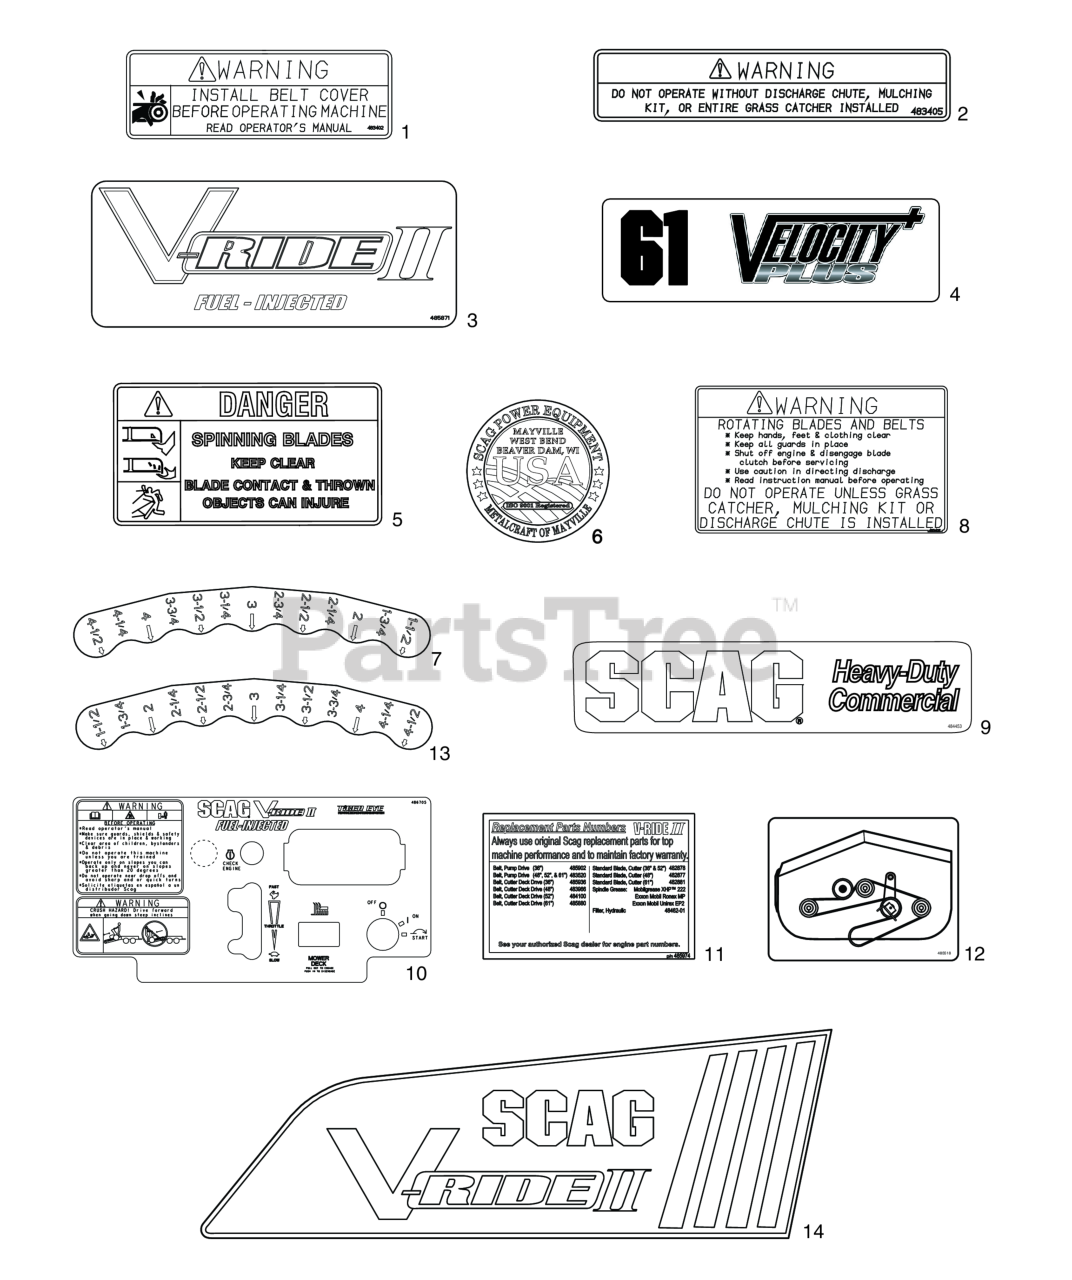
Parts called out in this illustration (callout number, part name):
1	Decal, Warning - Belt Cover
2	Decal, Warning-Discharge
3	Decal, Belt Cover
4	Decal, 36 Advantage 483060
5	Decal, Spinning Blades
6	Decal, Metalcraft - USA
7	Decal, Deck Height - Outer
8	Decal, Warning - Rotating Blades
9	Decal, Scag Heavy Duty Commercial
10	Decal, Instrument Panel - SVRII-32A/36A
11	Decal, SVRII Replacement Parts
12	Decal, Belt Routing - SVRII36A
13	Decal, Deck Height - Inner
14	Decal, Scag V-Ride II (Fuel Tank)
